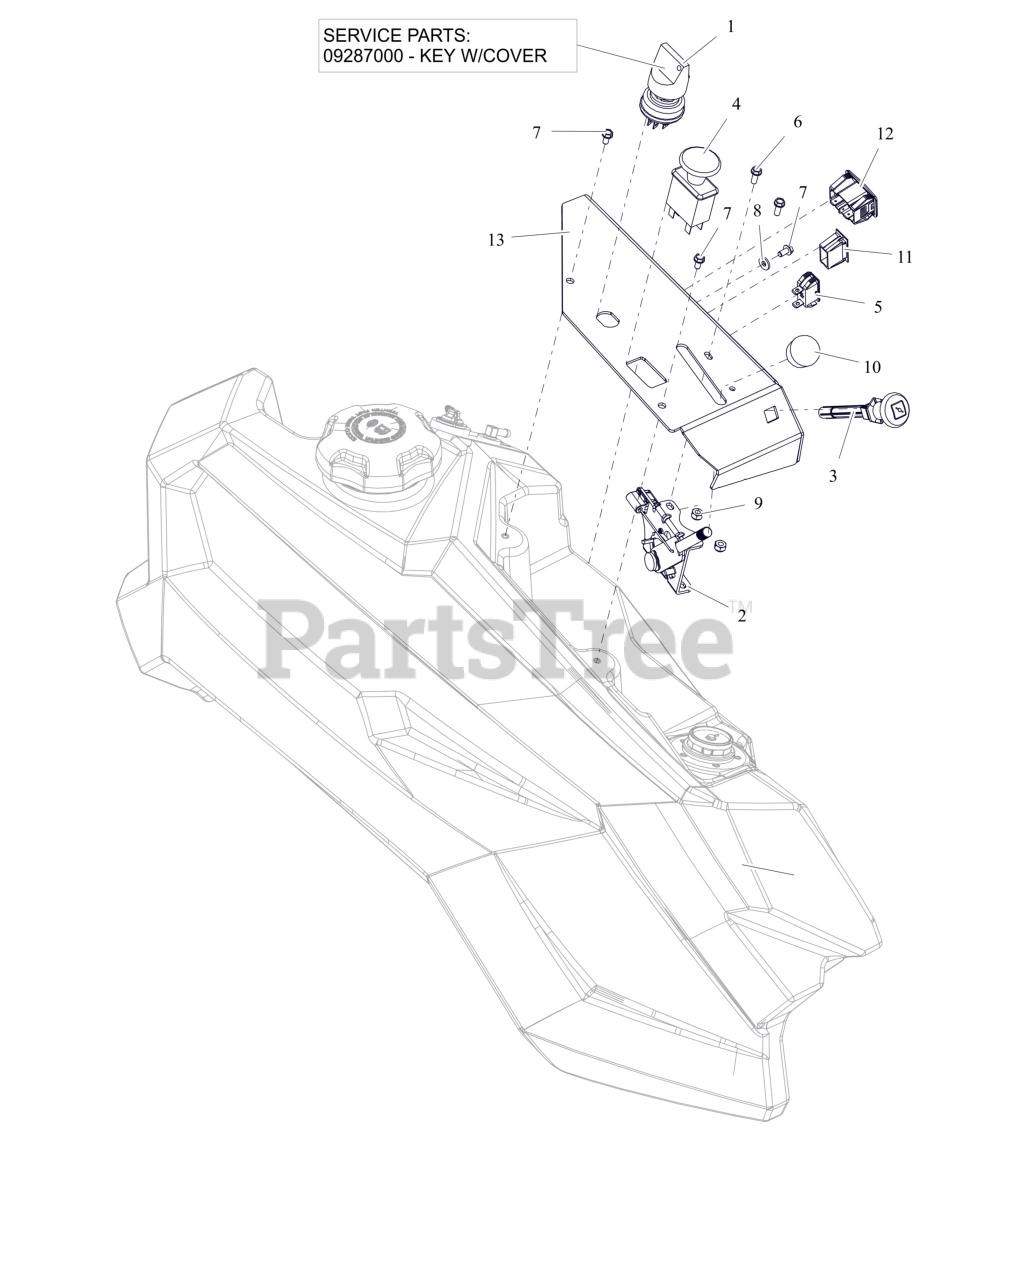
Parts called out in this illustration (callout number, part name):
1	SWITCH, IGNITION
1	KEY, W/ SHIELD
2	CABLE, PRO-CTRL 53.00"
3	CABLE, CHOKE (SNAP IN)
4	SWITCH, CLUTCH
5	LIGHT, INDICATOR (RED)
6	BLT, HWH #10-24X.50 ZCC
7	SCR-MCH 10-24X.38 HWHSTAINLESS
8	WSHR-FL-STL .196X.50X.06 ZC120
9	NUT-LK-NYL #10-24 G2 ZCC
10	KNOB-CONTROL-BLACK .38-16X.50
11	SWITCH,BLANK
12	HOUR METER
13	PANEL- RH CONTROL (RED)
